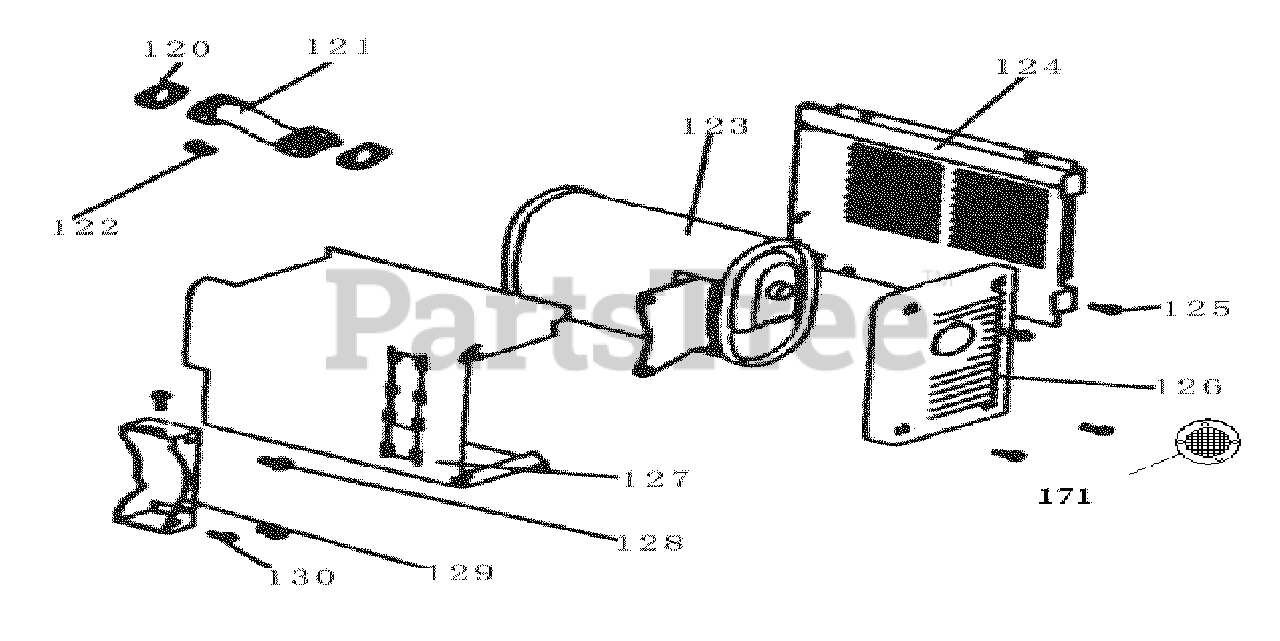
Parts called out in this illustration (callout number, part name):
121	Muffler pipe
124	Muffler cover
125	M6 x 12 flanged bolt
126	Muffler cover
127	Muffler cover
128	M8 x 20 bolt
129	Muffler cover frame
130	M8 x 16 flanged bolt
171	SPARK ARRESTOR
